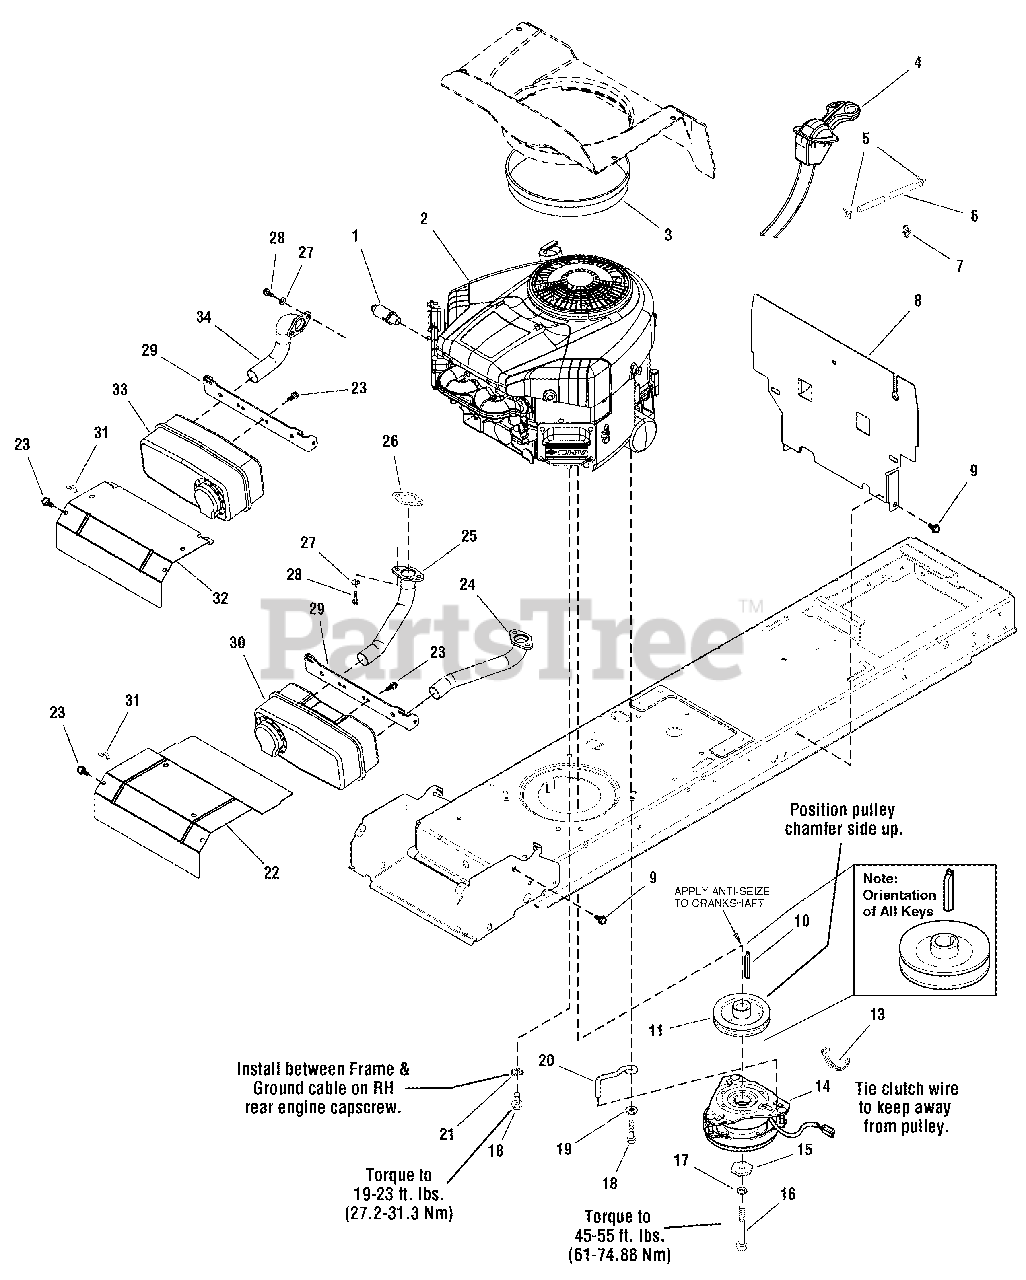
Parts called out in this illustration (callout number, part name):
1	VALVE, Oil Drain
2	** ENGINE, 18HP B&S Intek 1 Cylinder, Model 31P777-0121-B1
2	** ENGINE, 20HP B&S Intek Twin, Model 406577-0143-B1
3	EDGING, Rubber, Short
3	EDGING, Rubber, Long
4	CONTROL, Throttle Double 20.5, 23.5 B&S Single
4	CONTROL, Throttle Double 34.7, 36 B&S Twin
5	CLAMP, Hose Type E
6	HOSE, Fuel, 45-1/2" Long
6	HOSE, Fuel 55" Long
7	CLIP, Hose, Plastic, Push-In
8	SHIELD, Heat
9	SCREW, Taptite, 5/16-18 x 5/8
10	KEY, Hi-Pro, 1/4 x 2-1/2
11	PULLEY
13	TIE, Self Locking 7-5/16
14	CLUTCH ASSEMBLY, Long OGURA
15	WASHER
16	CAPSCREW, 7/16-20 x 3-1/2, Hex Head
17	LOCKWASHER, 7/16
18	SCREW, Hex, Washer Head, Taptite, 3/8-16 x 1-1/4
18	CAPSCREW, Hex Head, Taptite, 3/8-16 x 1-1/2
19	WASHER, 3/8
20	RETAINER, Clutch, Yellow
21	LOCKWASHER, External Tooth, 3/8
22	SHIELD, Heat B&S Twin 20GA
23	SCREW, Taptite, 1/4-20 x 1/2
24	PIPE, Exhaust w/Flange LH B&S INT
25	PIPE, Exhaust w/Flange RH B&S INT
26	GASKET, Exhaust B&S
27	LOCKWASHER, 5/16
28	CAPSCREW, Socket Head, 5/16-18 x 3/4
29	BRACKET, Muffler Mount 12GA
30	MUFFLER, B&S Twin
31	CLIP, Wire
32	SHIELD, Heat Single Cycle 20GA
33	MUFFLER, B&S Single
34	PIPE, Exhaust w/Flange B&S 1 Cycle
